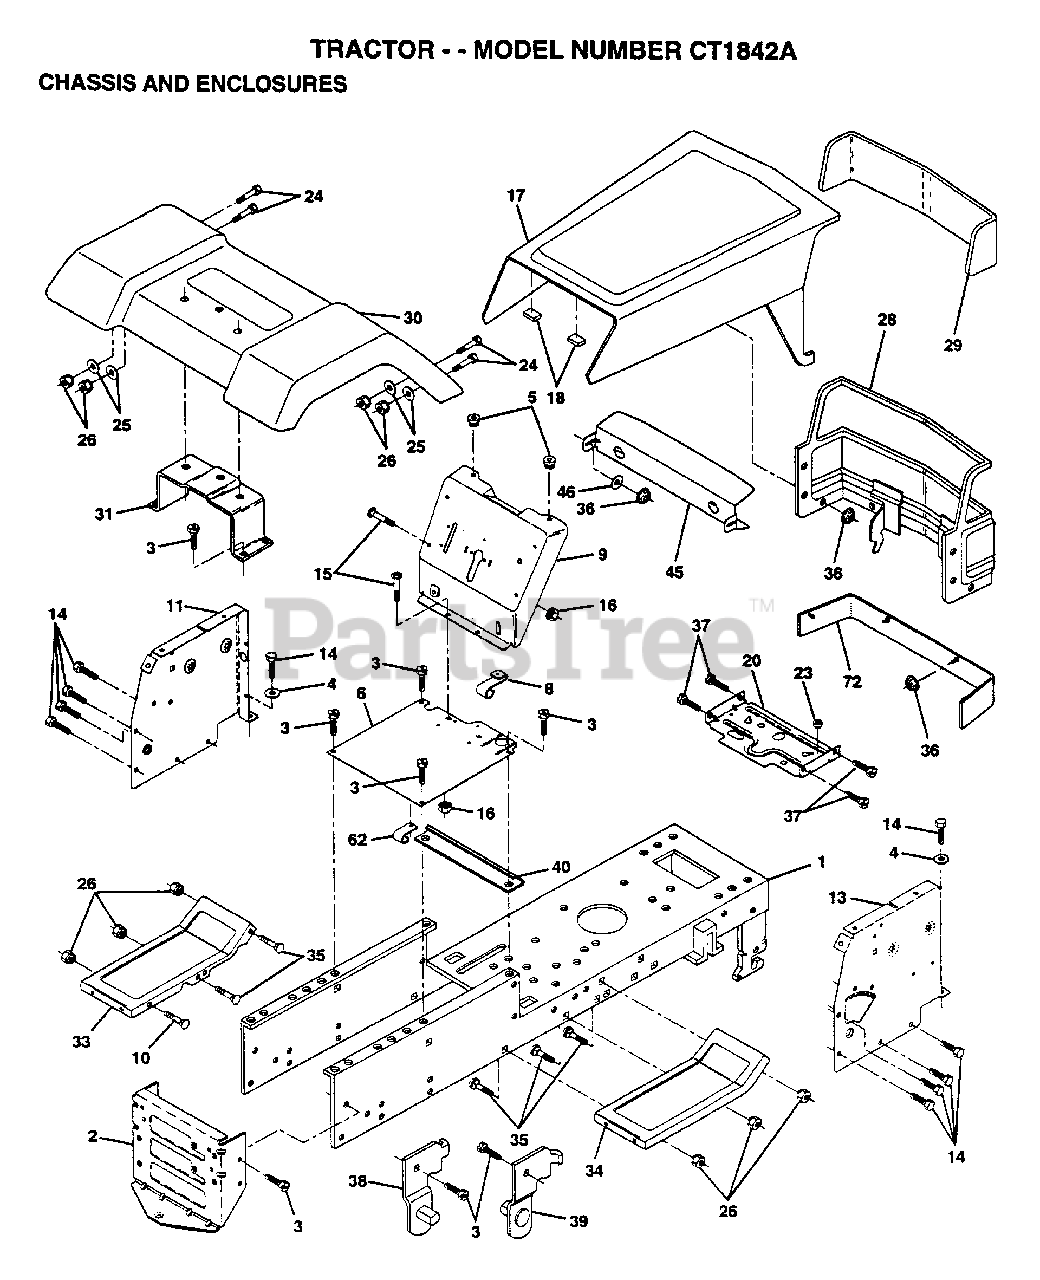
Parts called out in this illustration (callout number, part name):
1	CHASSIS.WLD.11GA
3	SCREW
4	WASHER
6	SADDLE.SLKSCR.6SP
8	"CLIP,INSULATOR"
11	DASH PANEL LH
14	SCREW LT
15	SCREW
24	BOLT
25	WASHER
26	NUT
28	GRILLE.WLD.RLY.LT
30	FENDER
31	BRACKET SUPT FEND
33	FOOTREST LH
34	FOOTREST RH
35	BOLT
36	PAL NUT LT
37	SCREW
38	BRACKET ASM LH
39	BRACKET ASM RH
40	SPACER FENDER LT
41	PLATE EXTEN FEND
43	WASHER
46	RETAINER
56	BOLT
72	STRAP ASM GRILL
